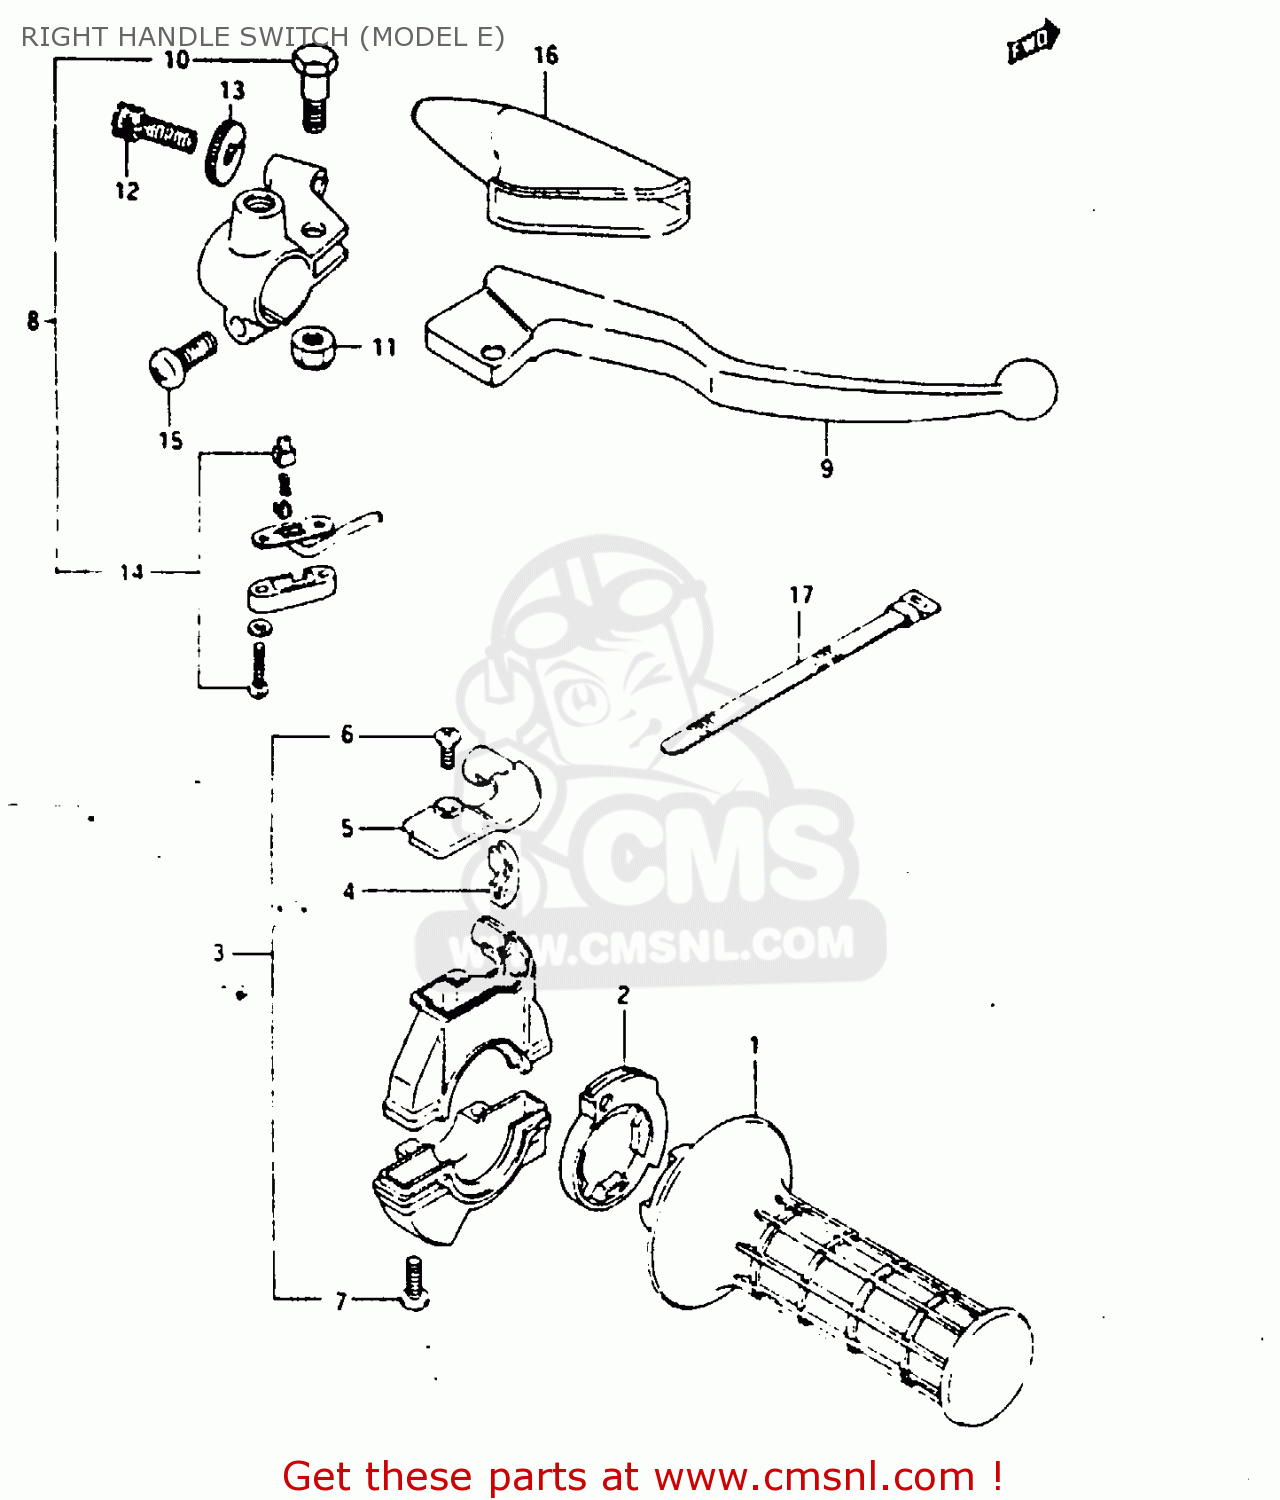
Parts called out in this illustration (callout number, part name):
1	GRIP, THROTTLE
2	ROTOR,THROTTLE GRIP
3	CASE ASSY,THROTTLE
4	GUIDE PIECE,THROTTLE
5	COVER,THROTTLE CASE
6	SCREW
7	SCREW
8	BRAKE LEVER & SWITCH ASSY
9	LEVER,BRAKE
10	BOLT,LEVER
11	NUT 6MM
12	ADJUSTER,CABLE
13	NUT,CABLE ADJUSTER
14	SWITCH ASSEMBLY
15	SCREW
16	COVER,CLUTCH LEVER
17	CLAMP(L:120)
